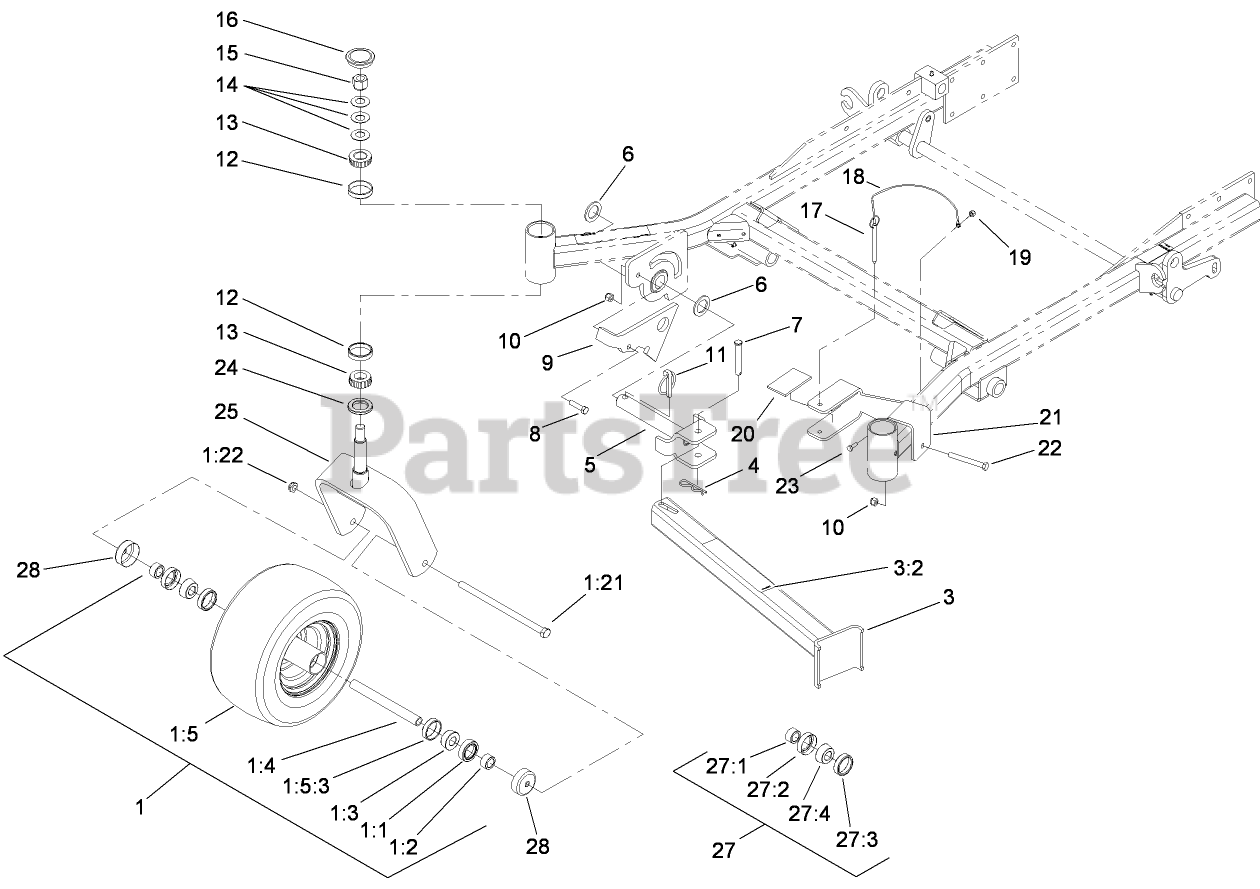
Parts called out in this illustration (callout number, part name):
1	CASTOR WHEEL ASM
1:1	SEAL-BEARING
1:2	SPACER-BEARING
1:3	BEARING-CONE, TAPER
1:4	SPACER-CASTER, FRONT
1:5	WHEEL AND TIRE ASM (SEMI-PNEUMATIC)
1:5:3	BEARING-CUP
1:21	SCREW-HH
1:22	NUT-LOCK, NI
3	Leg ASM
3:2	DECAL-Z STAND
4	PIN-HAIR
5	PIN-PIVOT
6	WASHER-THRUST
7	PIN-CLEVIS
8	SCREW-HH
9	BRACKET-LATCH
10	NUT-LOCK, NI
11	PIN-LYNCH
12	BEARING-CUP, TAPERED
13	BEARING-CONE, TAPERED
14	WASHER-BELLVILLE
15	NUT-LOCK, NI
16	CAP-GREASE
17	PIN-HITCH, COTTERLESS
18	LANYARD-NYLON
19	NUT-LOCK, NI
20	Cushion-Rubber
21	BRACKET-CRADLE
22	SCREW-HH
23	SCREW-HH
24	SEAL-GREASE
25	CASTER-FORK
27	CASTER WHEEL BEARING KIT
27:1	SPACER-BEARING
27:2	SEAL-BEARING
27:3	BEARING-CUP
27:4	BEARING-CONE, TAPER
28	GUARD-SEAL
